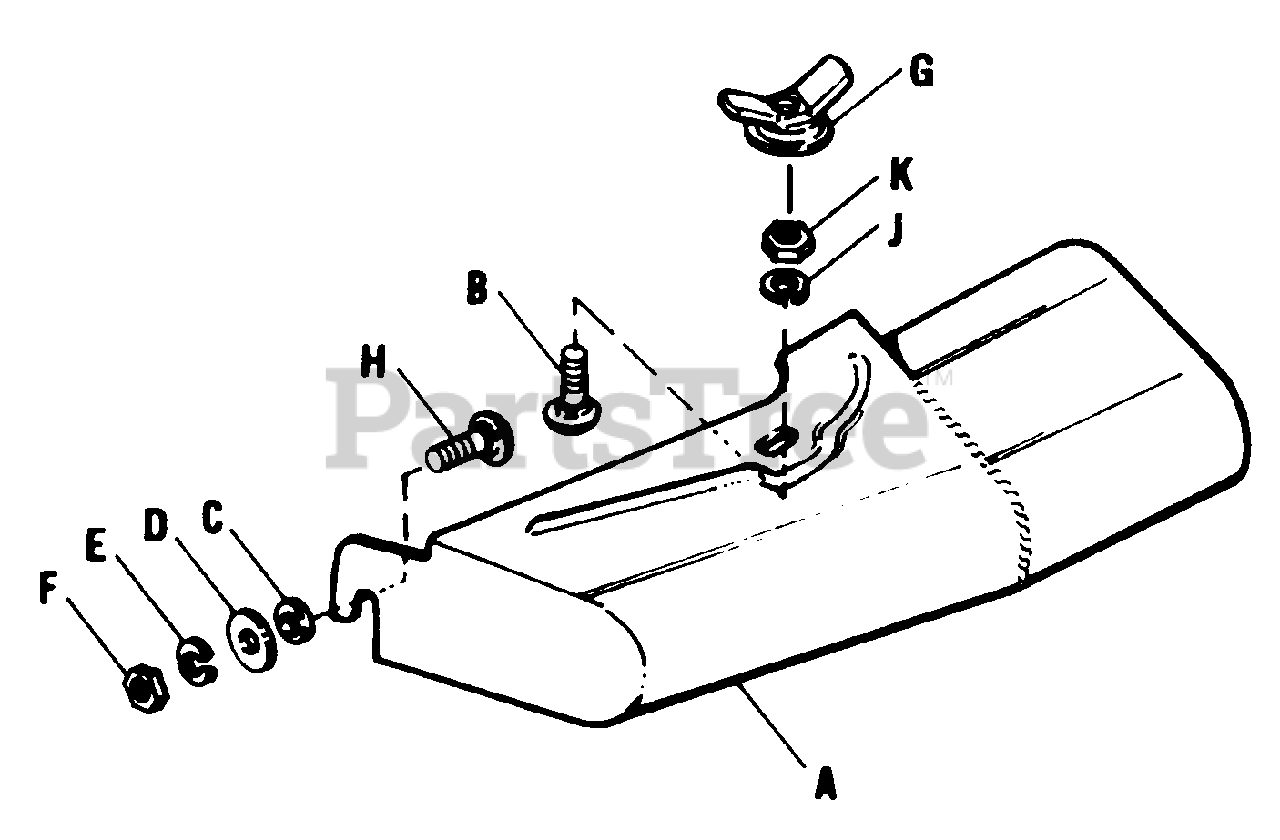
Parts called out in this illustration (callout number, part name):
A	Housing Assembly
B	Carriage Bolt 3/8-16 x 1-1/4" lg.
E	Lock Washer 3/8"
F	Hex Nut, Full 3/8-16
G	Nut Assembly
H	Carriage Bolt 5/16-18 x 1" lg.
J	Lock Washer 5/16"
K	Hex Nut, Full 5/16-18
